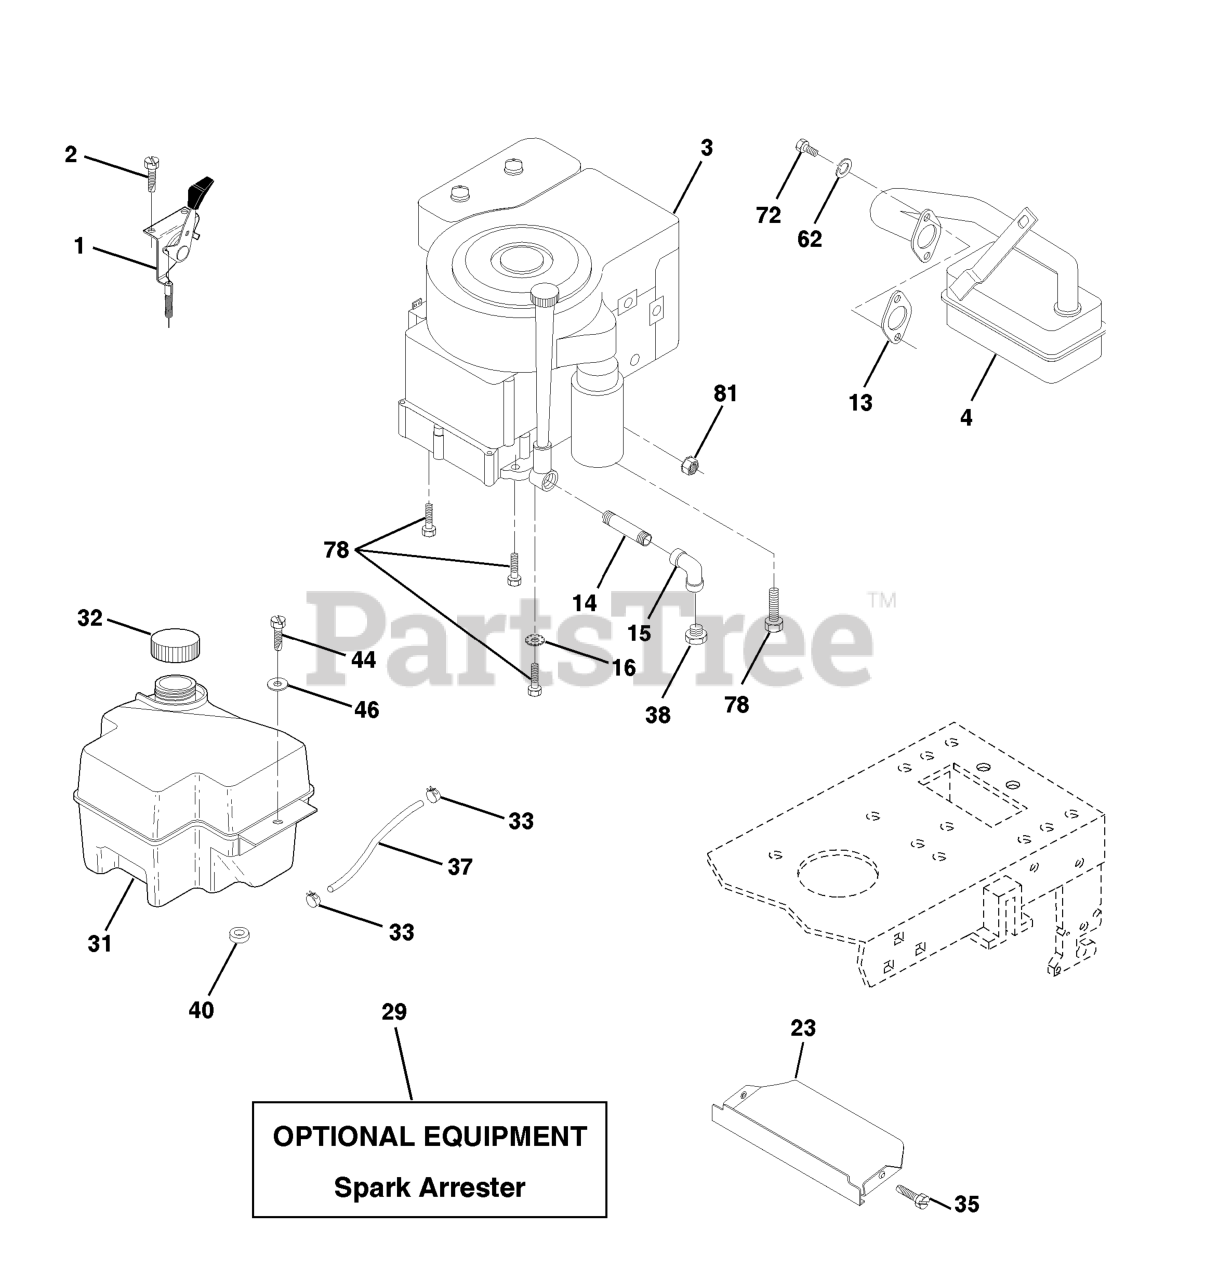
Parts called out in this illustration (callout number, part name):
1	CHOKE CONTROL
2	SCREW LT
4	MUFFLER.SINGLE.B&S.10-12HP
13	REPL BY 532 27 22-93
14	Nipple Pipe 3/8 Npt X 3"
15	ELBOW
16	LOCKWASHER
29	KIT.SPARK ARRESTOR 794945 B&S
31	FUEL TANK
32	FUEL CAP
33	HOSE CLAMP
35	SCREW.THDROL.5/16-18X3/4.TTY
37	LINE.FUEL.20
38	Plug Oil Drain
40	BUSHING.SNAP.NYL.BLK.
44	SCREW HEX CRT
46	WASHER
62	WASHER.LOCK.HVY.HLCL.SPR.5/16
72	SCREW
78	SCREW
81	NUT FLANGE 1/4-20 STARTER NUT
